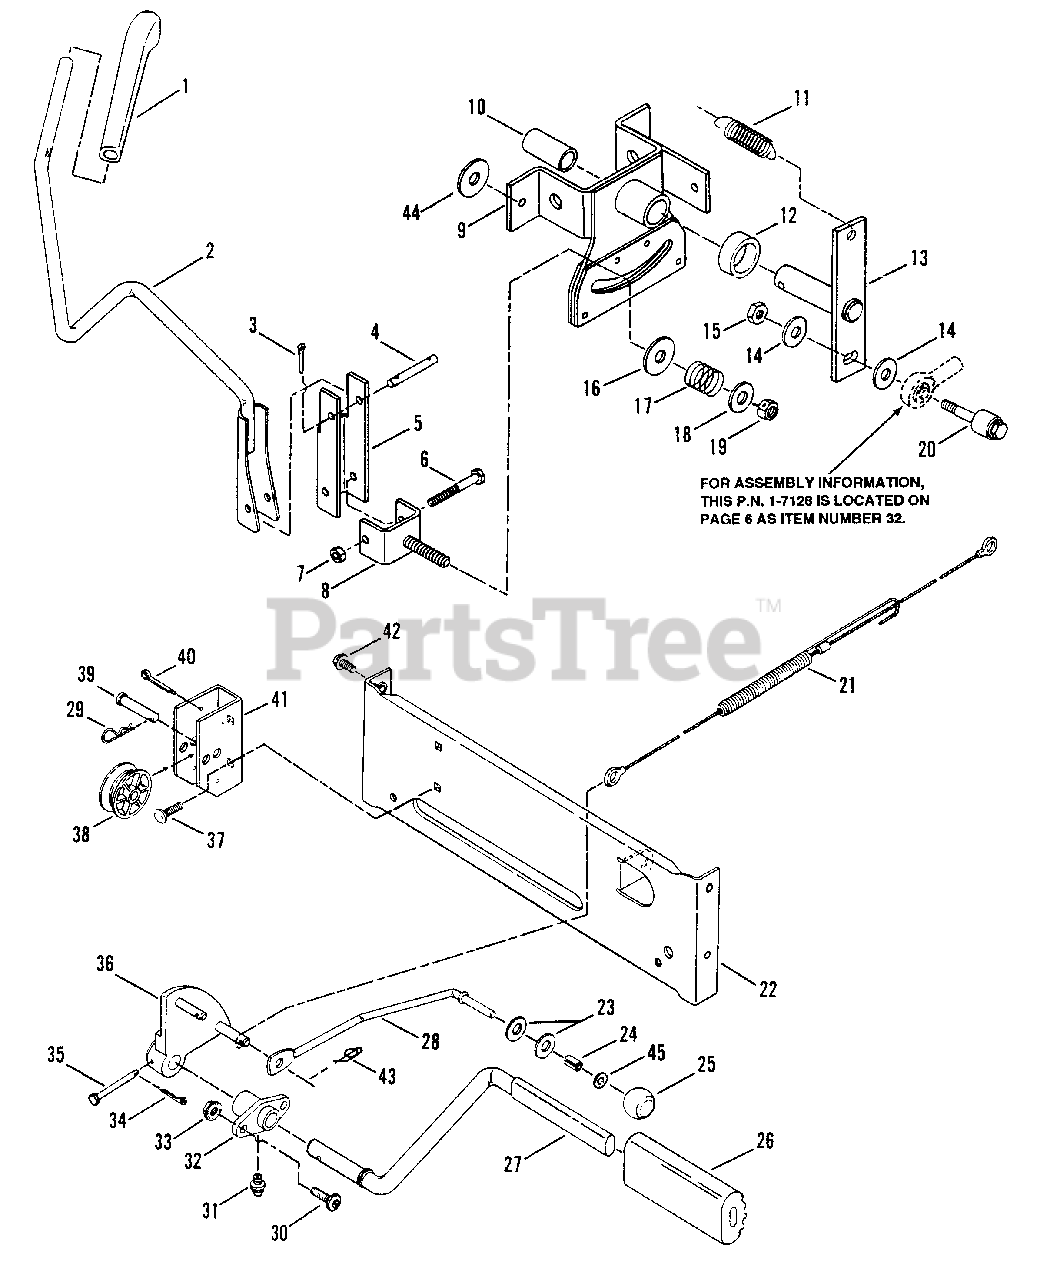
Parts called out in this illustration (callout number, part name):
1	KNOB, Shifter (Elongated)
2	SHIFTER, Transmission
3	PIN, 3/32 x 3/4" Cotter
4	PIN, Shifter
5	EXTENSION, Hub
6	SCREW, 1/4-28 x 2" Hex Head Cap
7	NUT, 1/4-28 Hex Lock
8	ASSEMBLY, Rub Plate
9	ASSEMBLY, Shift Pivot
10	BEARING, Shift Pivot Assembly (No longer available, try using 7015048)
11	SPRING, Shift
12	SPACER, 1.0 OD x .755 ID x .310 L
13	CONTROL, Speed
14	WASHER, 5/16 Flat
15	NUT, 5/16-24 Hex
16	WASHER, Special
17	SPRING, Tension
18	WASHER, 3/8" Flat
19	NUT, 3/8-24 Hex Lock
20	FOLLOWER, Cam
21	CABLE, Clutch (23.88" Long)
22	BRACE
23	WASHER, Nylon 5/16"
24	RING, Tolerance 5/16" x 1/2"
25	KNOB, Latch 5/16"
26	PAD, Pedal
27	PEDAL, Clutch/Brake
28	LATCH, Clutch/Brake
29	PIN, 1/4 x 1 1/8" Hair
30	SCREW, 5/16-18 x 7/8" Torx
31	FITTING, Lube 3/16"
32	PIVOT, Clutch/Brake Pedal
33	NUT, 5/16-18 Hex
34	PIN, 3/32 x 1" Cotter
35	PIN, 3/16 x 1 1/2" Clevis
36	BRAKE ARM
37	BOLT, 1/4-20 x 3/4" Short Neck Carriage
38	SPOOL, Bracket
39	PIN, 3/8 x 1 9/32" Clevis
40	PIN, 1/8 x 1 1/4" Cotter
41	BRACKET, Spool (No longer available, try modifying 7033328 to fit)
42	SCREW, 5/16-18 x 1/2" Self-Tapping
43	PIN, 1/16 x 1 7/32" Self-Lock Cotter
44	WASHER, 13/32 I.D. x 1 3/8" O.D.
45	RETAINER, 5/16
